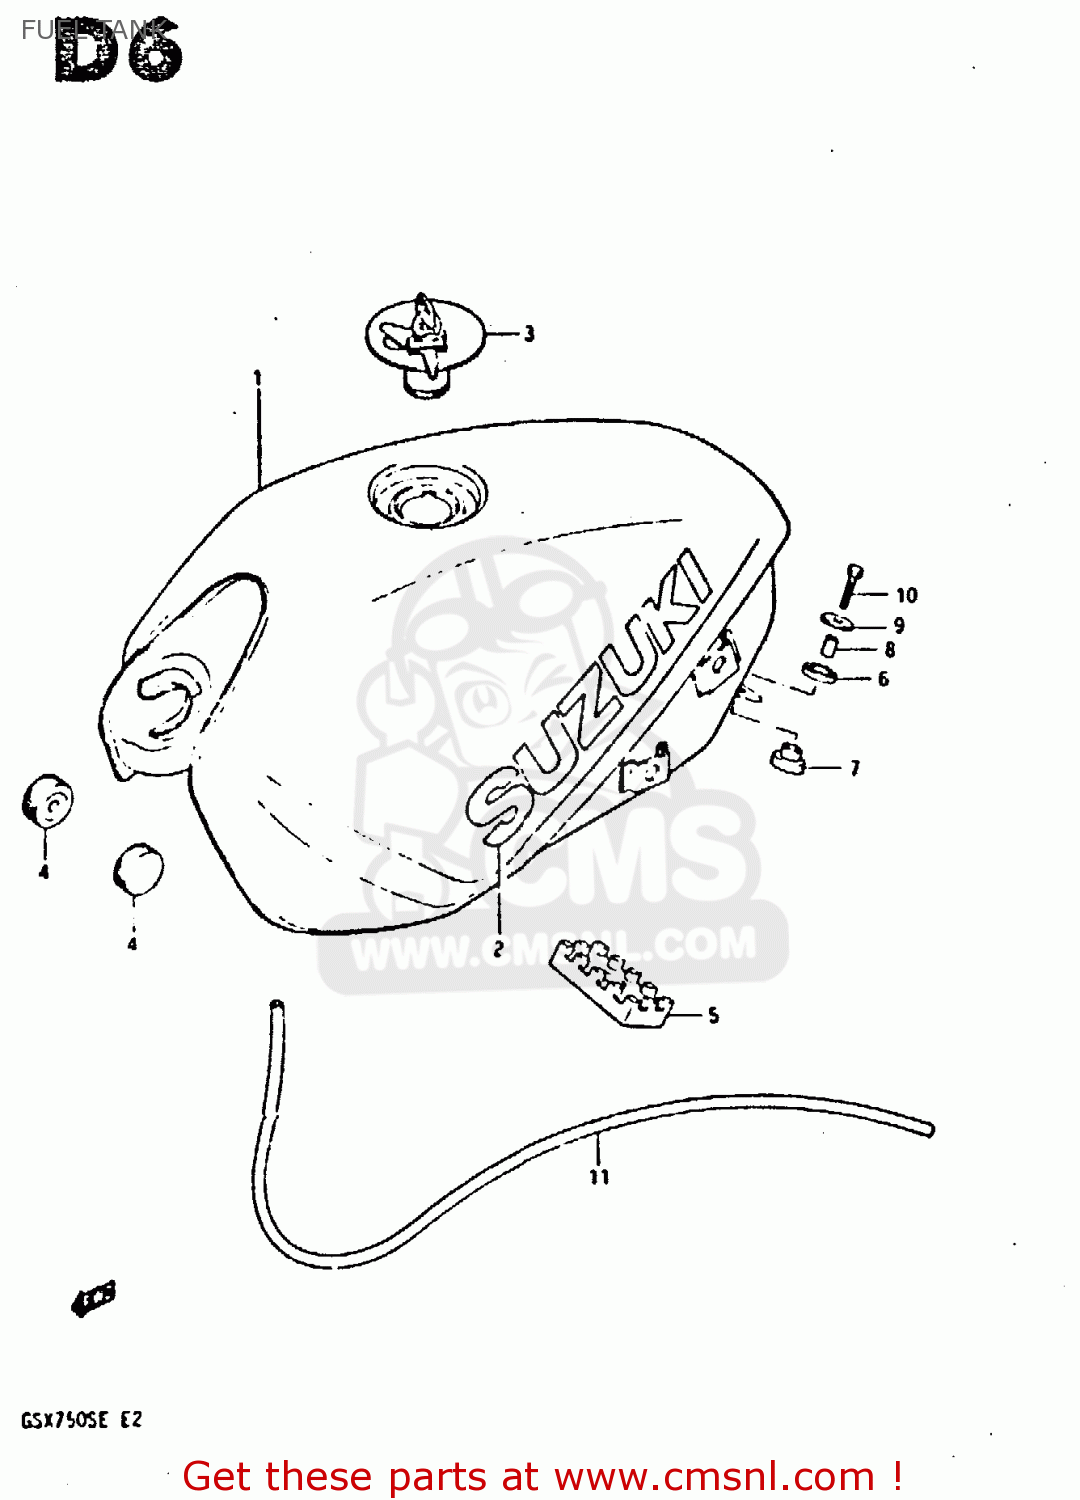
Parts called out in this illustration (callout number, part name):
1	TANK ASSY, FUEL (WHITE)
2	EMBLEM
3	CAP ASSY,FUEL TANK
4	CUSHION
5	CUSHION,FUEL TANK CTR
6	CUSHION
7	CUSHION
8	SPACER
9	WASHER (6.5X24X1.6)
10	BOLT
11	HOSE,FUEL
